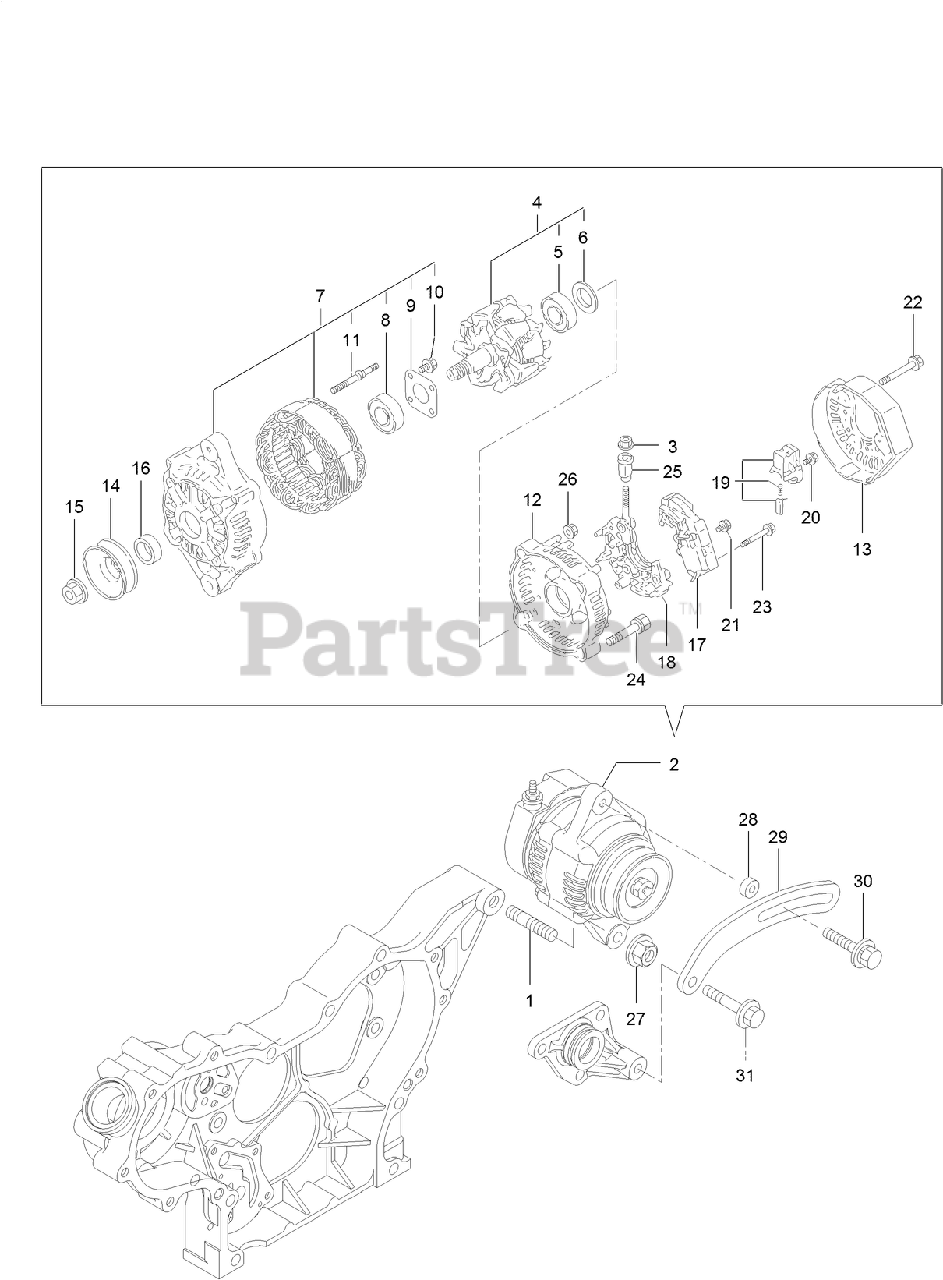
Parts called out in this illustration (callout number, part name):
2	ALTERNATOR
4	ROTOR ASM
5	BEARING-BALL
7	FRAME ASM
8	BEARING-BALL
9	PLATE-RETAINER
14	PULLEY
16	COLLAR
17	REGULATOR ASM
18	HOLDER
19	HOLDER
25	BUSHING-INSULATION
28	SPACER
29	ADJUSTER
30	BOLT-ADJUST
